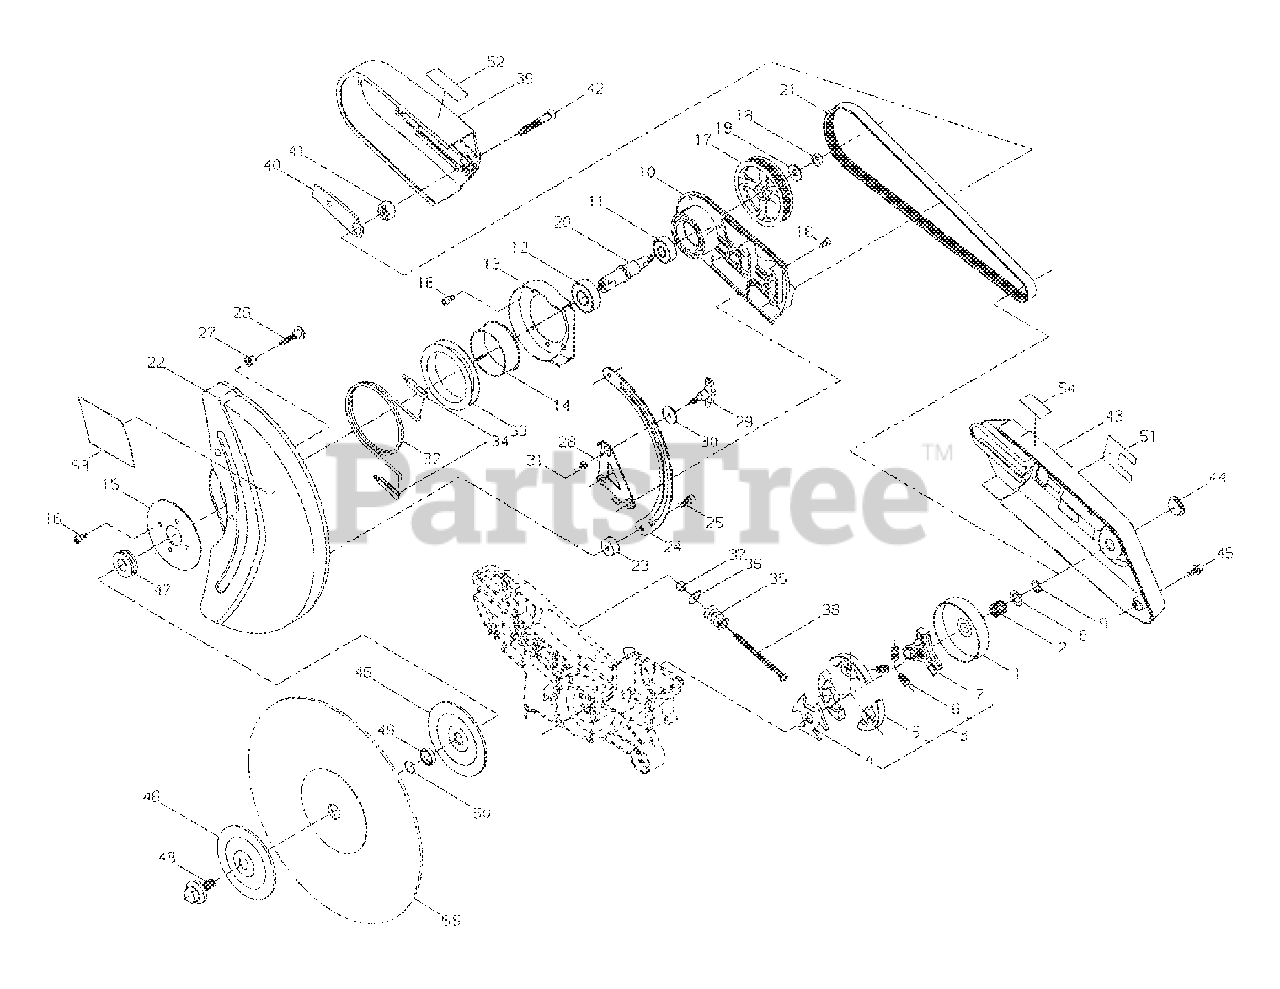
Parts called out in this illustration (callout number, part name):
1	DRUM, CLUTCH
2	BEARING, NEEDLE
3	CLUTCH ASSY
4	HUB, CLUTCH - INNER
5	SHOE, CLUTCH
6	SPRING, CLUTCH
7	HUB, CLUTCH - OUTER
8	PLATE, THRUST
9	RING, RETAINING - 13
10	CASE, BEARING
11	BEARING, BALL - 6201
12	BEARING, BALL - 6203
13	PLATE, SPRING
14	RING
15	PLATE, BEARING
16	SCREW - 5X16
17	PULLEY, DRIVE
18	NUT - 8
19	COLLAR
20	DRIVESHAFT
21	BELT, DRIVE
22	GUARD, WHEEL
23	COLLAR
24	SLIDE PLATE
25	SCREW - 6X20
26	BOLT, CLUTCH
28	PLATE, LOCK
29	KNOB
30	WASHER
31	NUT
32	SPRING
33	GUIDE, SPRING
34	SPRING HOLDER
35	SPRING
36	WASHER
37	NUT
38	SCREW
39	PULLY COVER
40	PLATE, TENSION
41	BLOCK, TENSION
42	SCREW - 8X50
43	COVER, CLUTCH
44	PLUG
45	SCREW - 5X14
46	FLANGE
47	COLLAR
48	BOLT - FLANGE
49	COLLAR
50	RING, RETAINING
51	LABEL - TRADE
52	LABEL - INSTRUCTION
53	LABEL - CAUTION
54	LABEL - ARROW
55	CUT OFF WHEEL
